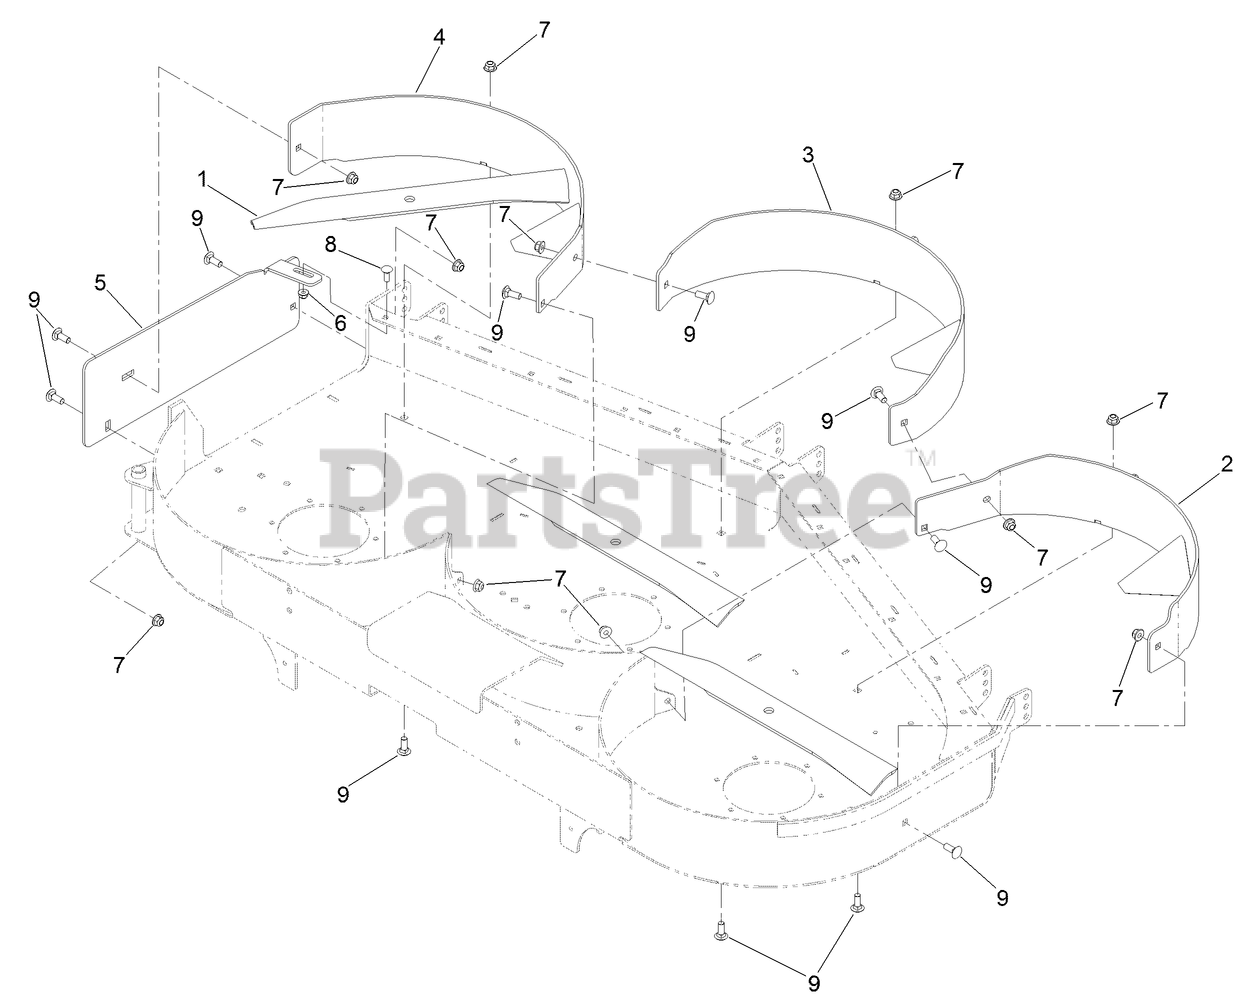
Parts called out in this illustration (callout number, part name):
1	BLADE-ROTARY, RECYCLING 20.5IN
2	BAFFLE-LH
3	BAFFLE-CENTER
4	BAFFLE-RH
5	PLATE-COVER, DISCHARGE
6	NUT-HF, NI
7	NUT-HF, NI
8	SCREW-CARR
9	BOLT-CARR
